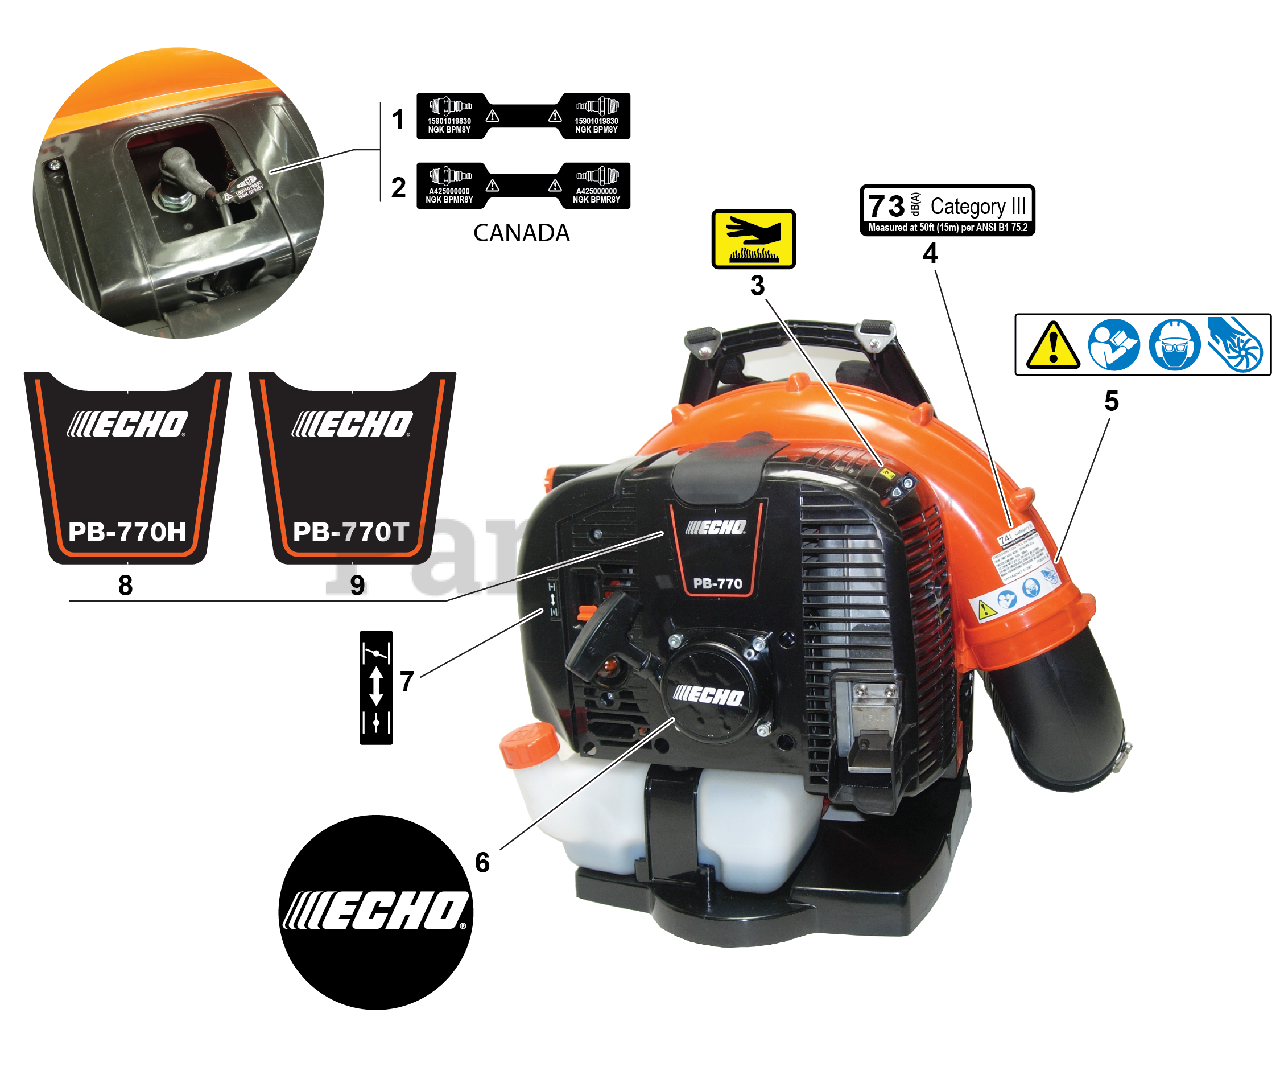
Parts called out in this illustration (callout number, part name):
1	LABEL - SPARK PLUG -- BPM8Y
2	LABEL - SPARK PLUG -- BPMR8Y
3	LABEL - HOT SURFACE
4	LABEL - NOISE -- 73dB(A) CAT III
5	LABEL - CAUTION
6	LABEL - ECHO
7	LABEL - CHOKE
8	LABEL - MODEL -- PB-770H
9	LABEL - MODEL -- PB-770T
